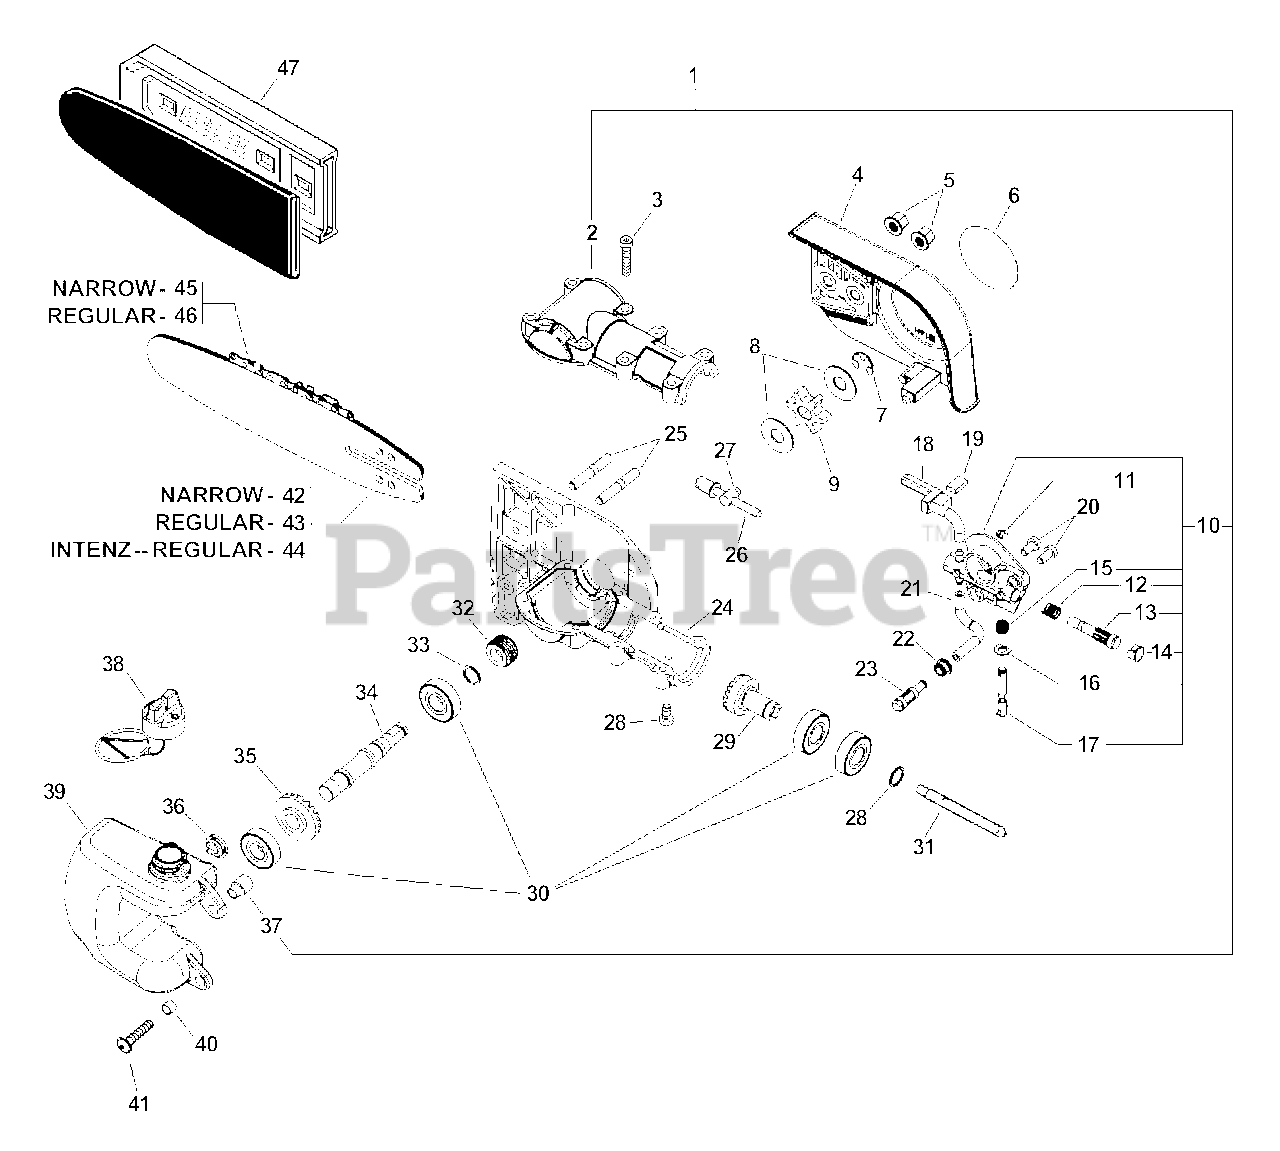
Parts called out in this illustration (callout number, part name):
1	OILER/GEAR CASE ASSY
2	CASE, GEAR - UPPER Ø35
3	SCREW M5×.25
4	GUARD, SPROCKET
5	NUT, FLANGE M6
6	LABEL, ECHO
7	RING, RETAINING Ø0.300
8	WASHER 10.2×24.5×1.2
9	SPROCKET, DRIVE
10	AUTO-OILER ASSY
13	PLUNGER ASSY
14	CAP, OIL PUMP
17	ADJUSTER, OILER
18	PIPE, OIL OUTLET
19	PAD, FOAM
20	SCREW M5×.8×10
21	PIPE, IMPULSE 3×6×75
22	GROMMET
23	FILTER, OIL
24	CASE, GEAR
25	BOLT, STUD 6
27	TENSIONER, CHAIN
28	RING, SNAP Ø12
29	GEAR, BEVEL
30	BEARING, BALL 6201
31	CONNECTOR, DRIVE SHAFT
32	GEAR, WORM
33	RING, SNAP Ø12
34	SHAFT, GEAR
35	GEAR, BEVEL
36	VENT ASSY
37	COLLAR 6
38	CAP ASSY, OIL
39	TANK, OIL
40	SPACER 6.2×7.8×6
41	SCREW 5×28
42	GUIDE BAR - 10"
43	GUIDE BAR - 10"
44	GUIDE BAR - 10" -- INTENZ
45	SAWING CHAIN - 90SG - 10" -- MICRO-LITE
46	SAWING CHAIN - 91VS - 10" -- LOW PROFILE
47	COVER, GUIDE BAR
